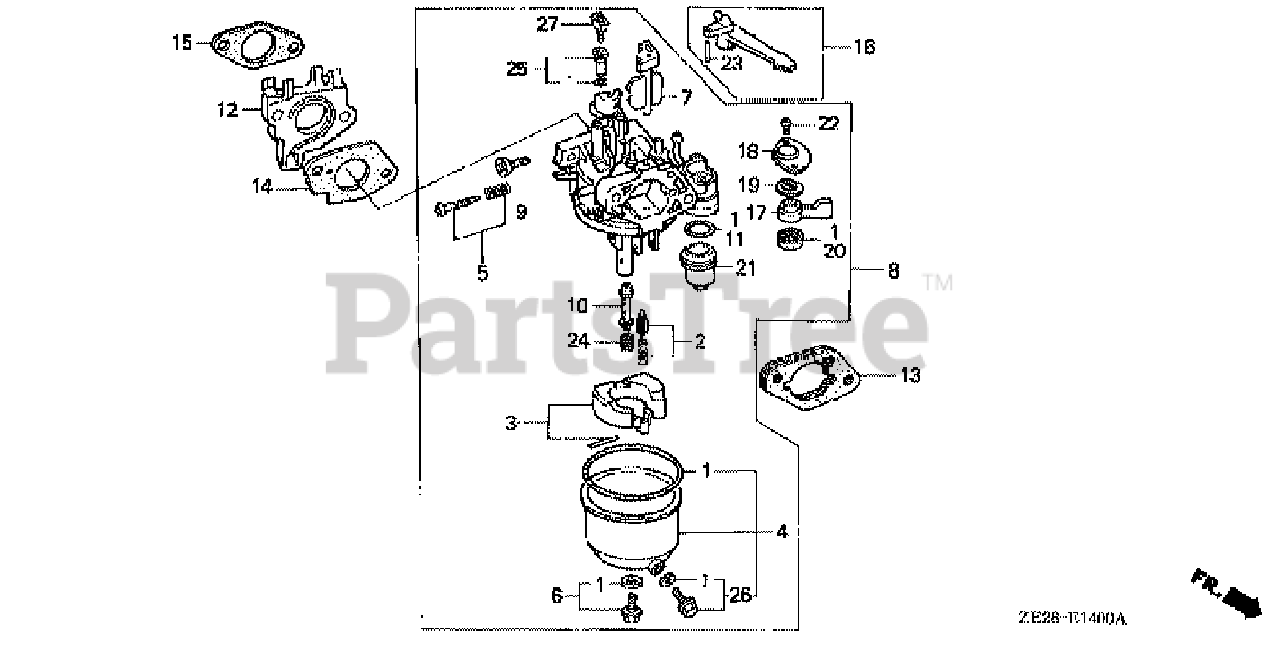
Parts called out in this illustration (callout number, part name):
1	GASKET SET
2	VALVE SET, FLOAT
3	FLOAT SET
4	CHAMBER SET, FLOAT
5	SCREW SET, PILOT
6	SCREW SET B
7	CHOKE SET
8	CARBURETOR ASSY. (BE15G A)
9	SCREW, THROTTLE STOP
10	NOZZLE, MAIN
11	GASKET, FUEL STRAINER CUP
12	INSULATOR, CARBURETOR
13	SPACER, CARBURETOR
14	GASKET, CARBURETOR
15	GASKET, INSULATOR
16	LEVER, CHOKE (STD)
17	LEVER, VALVE
18	PLATE, LEVER SETTING
19	SPRING, VALVE LEVER
20	GASKET, VALVE
21	CUP, FUEL STRAINER
22	SCREW, PAN (3X6)
22	SCREW, PAN (3X8)
23	PIN, SPRING (2X12)
24	JET, MAIN (#80)
24	JET, MAIN (#82)
24	JET, MAIN (#85)
25	JET SET, PILOT (#38)
